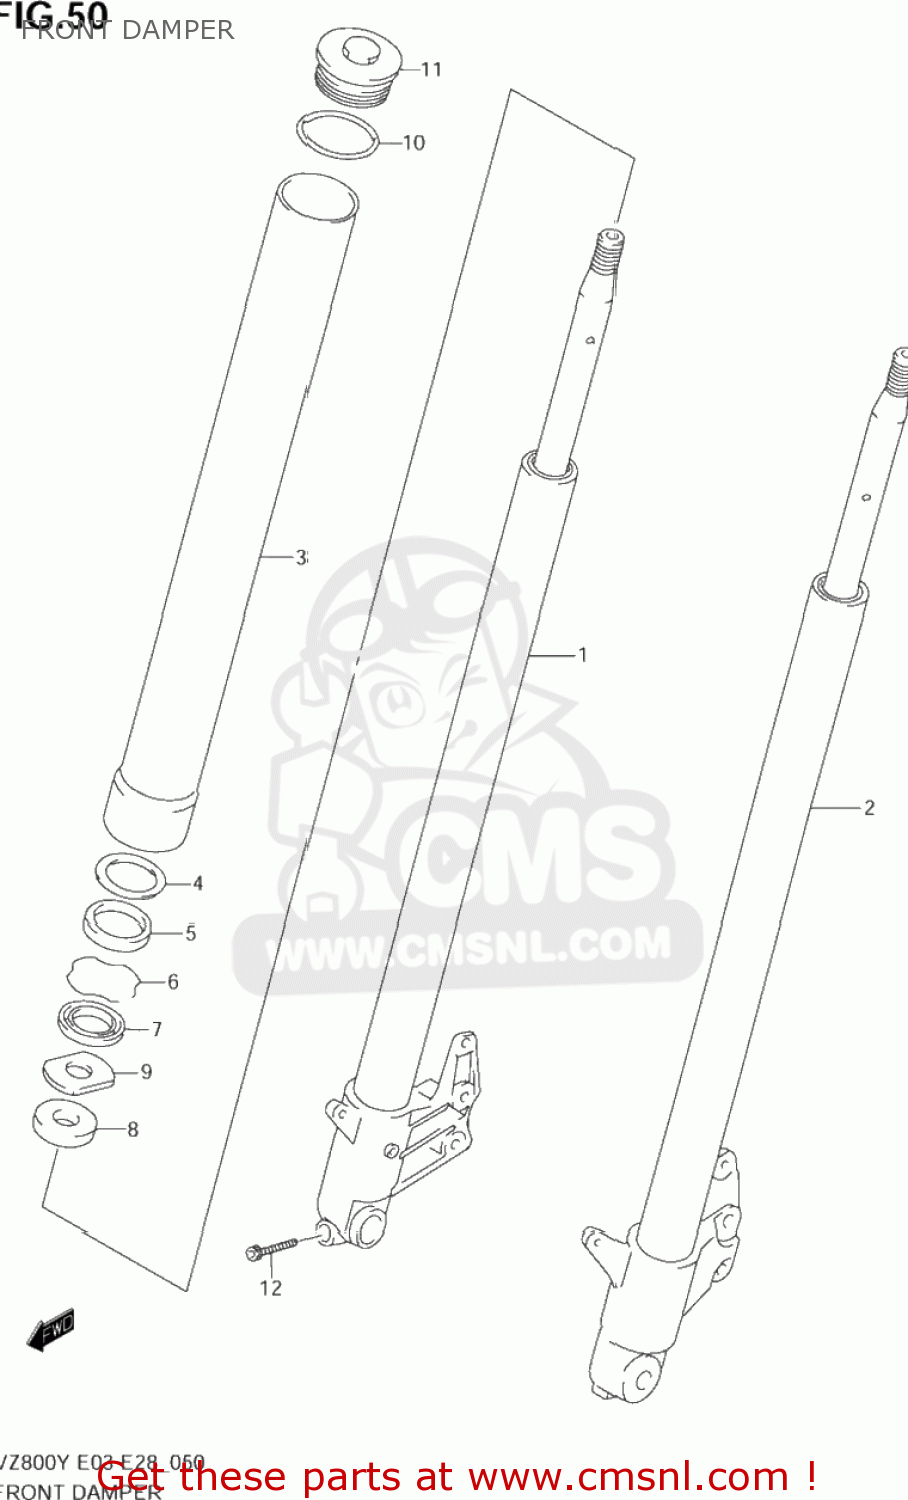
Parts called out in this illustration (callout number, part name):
1	DAMPER,FR FORK,R
2	DAMPER,FR FORK,L
3	TUBE,OUTER
4	WASHER,FORK OIL SEAL
5	SEAL,OIL
6	RING,OIL SEAL STOPPER
7	SEAL,DUST
8	RUBBER,CUSHION
9	NUT
10	O RING
11	CAP
12	BOLT,LWR
